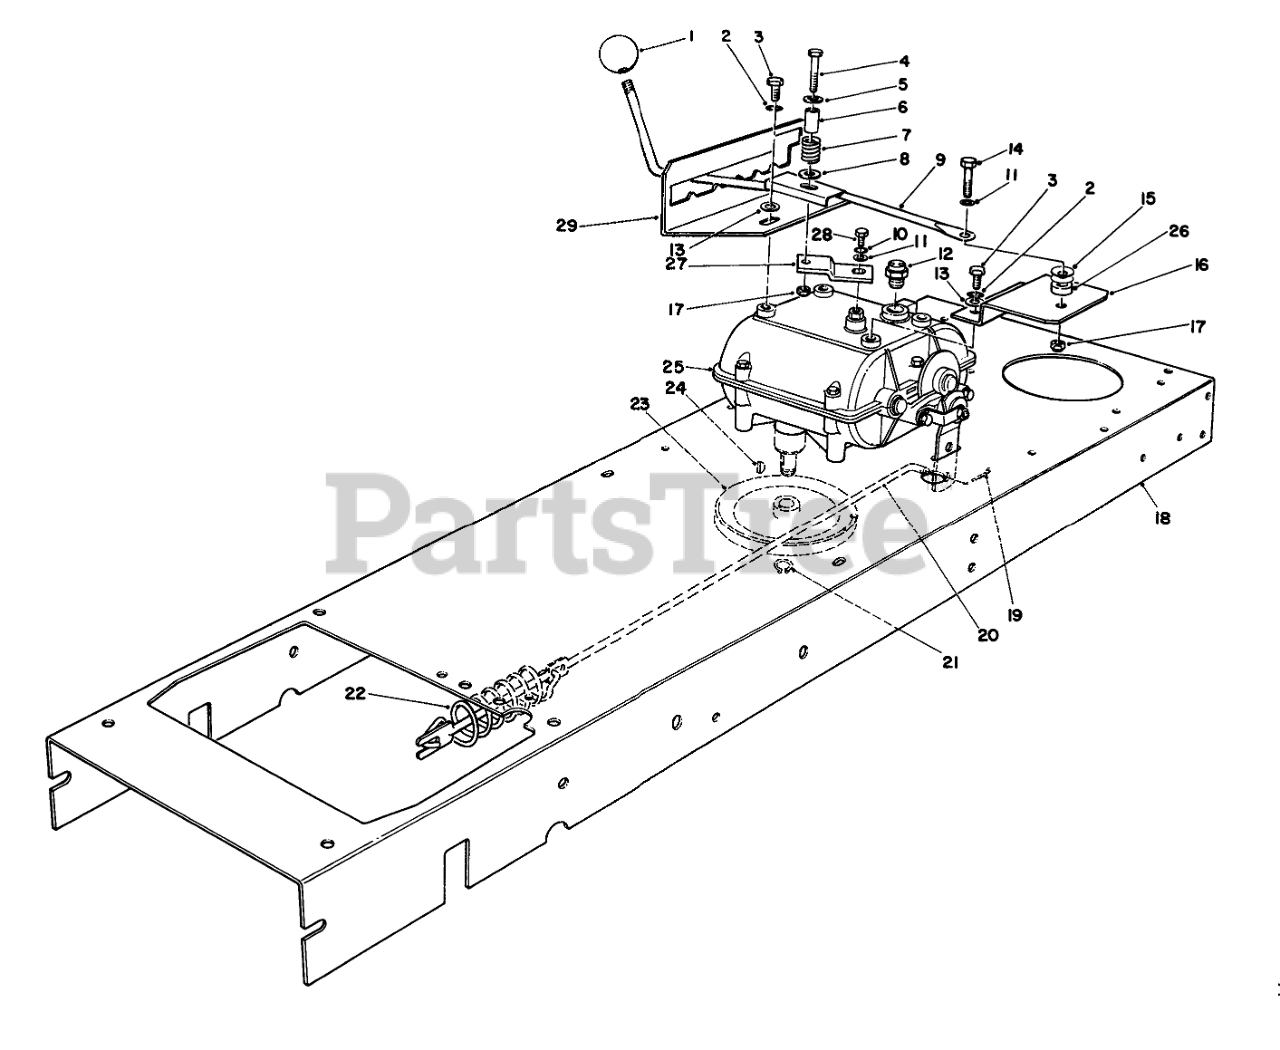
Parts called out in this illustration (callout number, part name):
2	WASHER-LOCK
3	SCREW-HWHTF
4	SCREW-HH
5	WASHER-FLAT
6	SPACER-SPLIT
7	SPRING-COMPRESSION
8	WASHER-FLAT
9	Lever-Shift
10	WASHER-LOCK
11	WASHER-FLAT
12	NEUTRAL SWITCH
13	WASHER-PLAIN
14	SCREW-HH
15	PUSH IN NUT
16	BRKT - SHIFTER MTG B
17	NUT-LOCK, NI
18	Frame-Main
19	Pin-Cotter
20	BRAKE ROD
21	RING-SNAP, EXTERNAL
22	SPRING-EXT
23	PULLEY
24	KEY-WOODRUFF
25	TRANSMISSION
26	SPACER-PIVOT
27	LEVER-SHIFT
28	SCREW-HH
29	Gate-Shift
